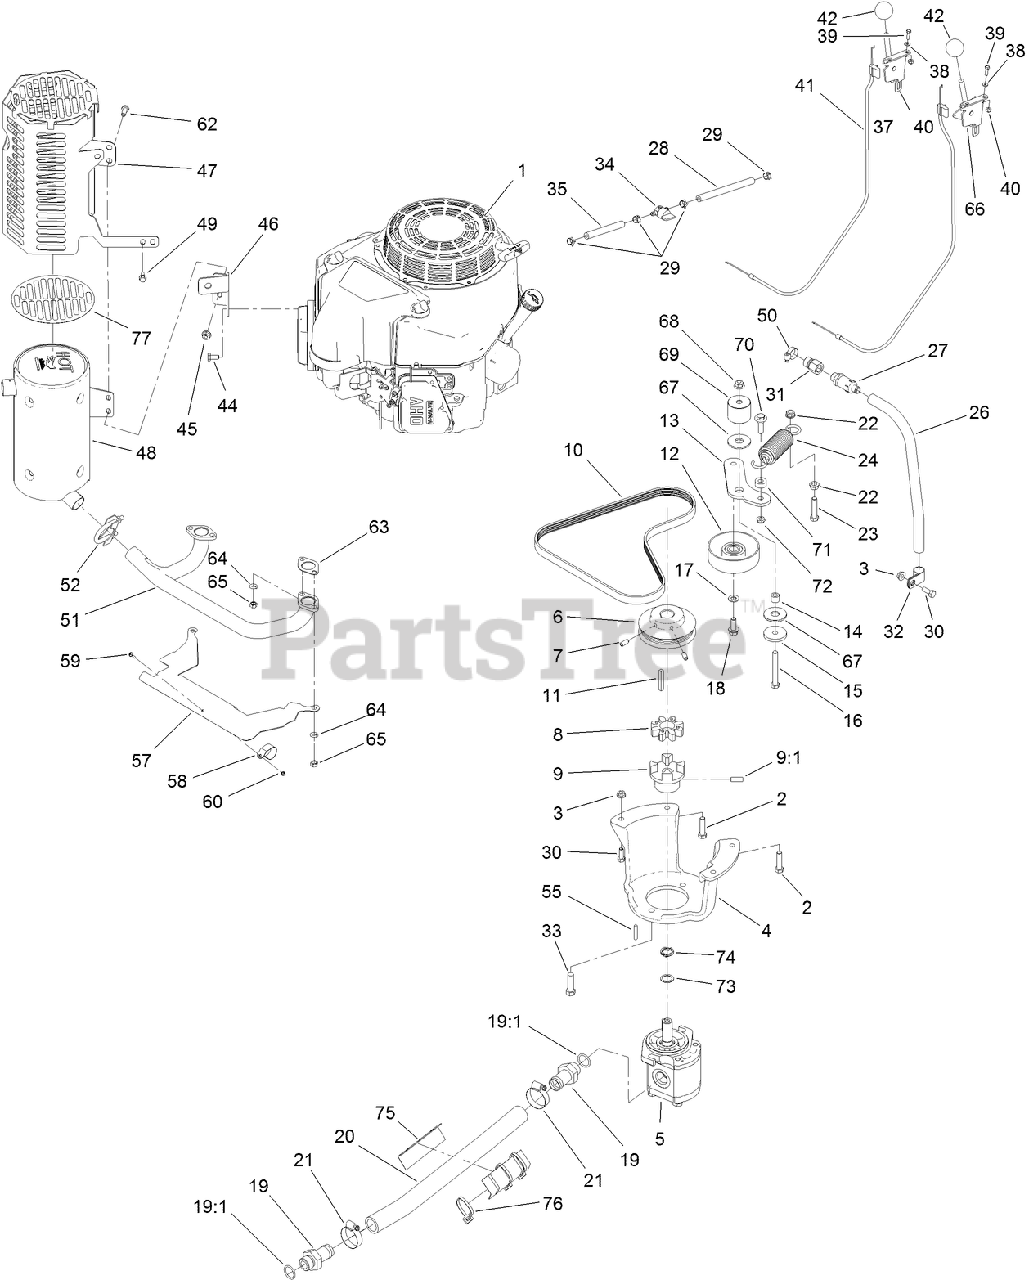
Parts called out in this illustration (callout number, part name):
1	ENGINE-KAWASAKI, FS481V
2	SCREW-HH
3	NUT-HF
4	MOUNT-PUMP
5	GEAR PUMP ASM
6	PULLEY-ENGINE
7	SCREW-SET, HSH
8	COUPLER-SPIDER
9	COUPLER-FLEX
9:1	SCREW-SET
10	BELT-V
11	KEY-SQUARE
12	PULLEY-IDLER
13	ARM-IDLER
14	BUSHING-LEVER, LIFT
15	WASHER-PLAIN
16	SCREW-HH
17	WASHER-FLAT
18	SCREW-HHF
19	FITTING
19:1	O-RING
20	HOSE-SUCTION
22	NUT-HHF, WHIZ
23	SCREW-HH
24	SPRING-EXTENSION
26	HOSE-VENT
27	VALVE-DRAIN, OIL
28	HOSE-FUEL
29	CLAMP-HOSE
30	SCREW-HH
31	Adapter
32	CLAMP-R
33	SCREW-HH
34	VALVE-FUEL
35	HOSE-FUEL
37	LEVER-CONTROL
38	WASHER-FLAT
40	NUT-LOCK, NI
41	CABLE-CONTROL
44	SCREW-HH
45	NUT-HF
46	BRACKET-GUARD, MUFFLER
47	GUARD-MUFFLER
48	MUFFLER
49	SCREW-HHF
50	CLAMP-HOSE
51	MANIFOLD-MUFFLER
52	CLAMP-MUFFLER
55	KEY-SQUARE
57	PLATE-SHIELD, HEAT
59	SCREW-PAN
60	NUT-HEX
62	SCREW-HH
63	GASKET-EXHAUST
64	WASHER-SPRING
65	NUT-HEX
66	LEVER-CONTROL
67	WASHER-FRICTION, COMPOSITE
68	NUT-HF, NI
69	SPACER-IDLER
70	SCREW-SHOULDER, HWH
71	SPACER
72	NUT-LOCK, NI
73	WASHER-THRUST
74	WASHER-WAVE
75	PROTECTOR-HOSE
76	TIE-CABLE
77	FOIL-GUARD
